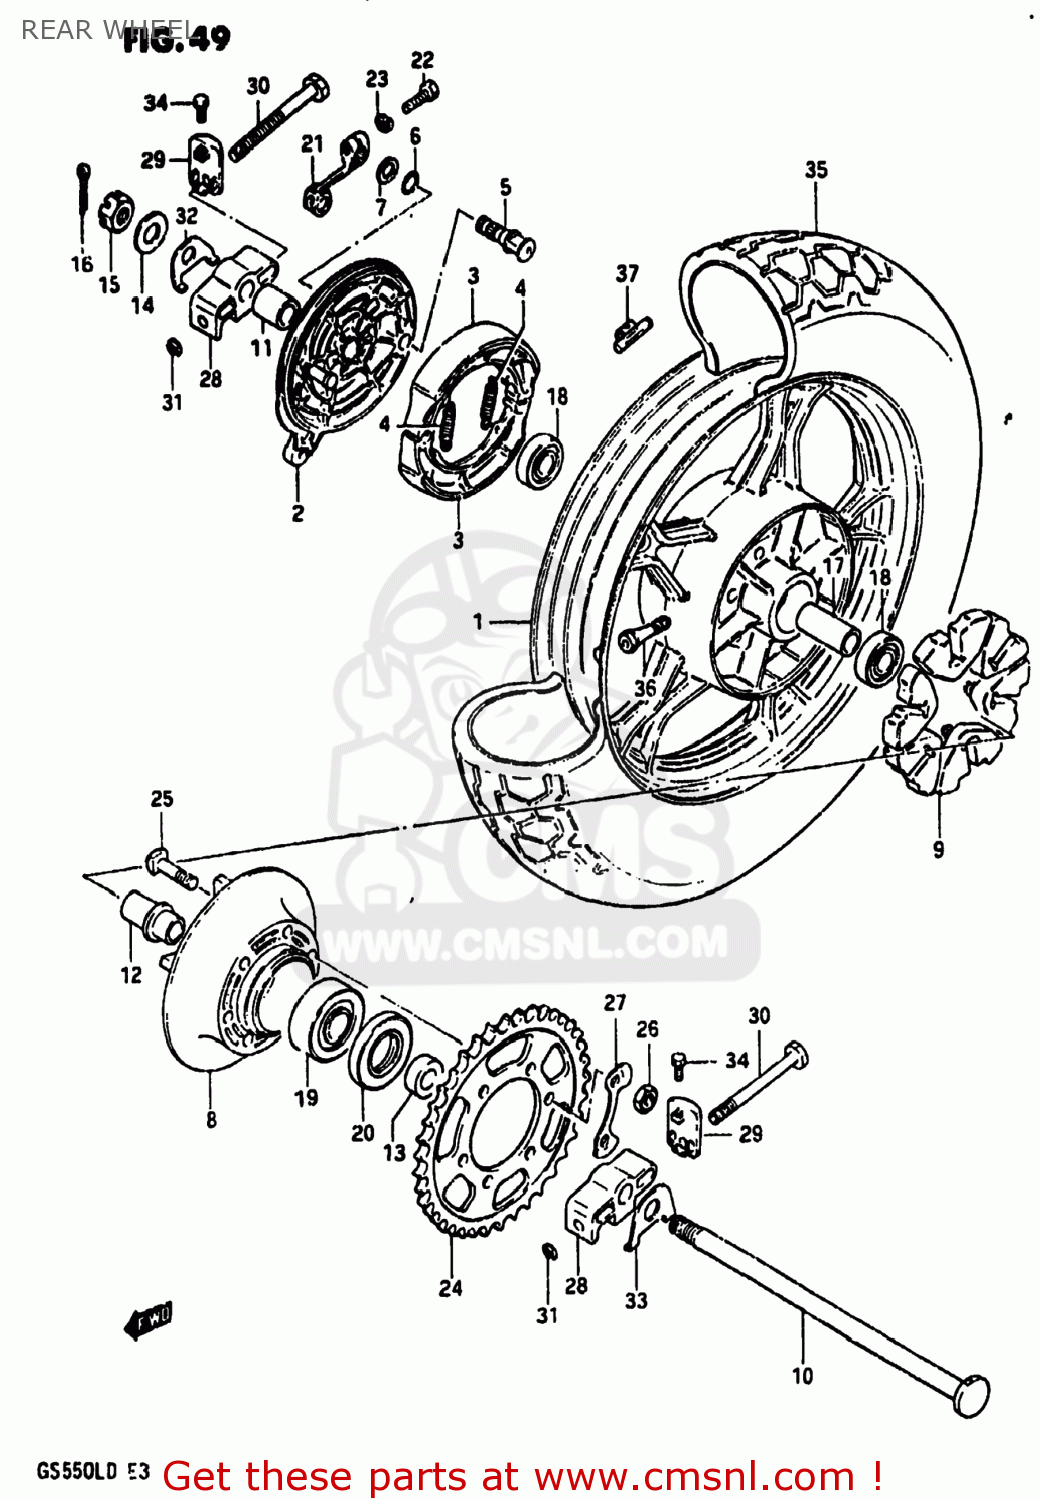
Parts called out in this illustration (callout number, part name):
1	WHEEL,REAR
2	PANEL,REAR HUB
3	SHOE,BRAKE
4	SPRING,BRAKE SHOE
5	CAM,FRONT BRAKE
6	O-RING,BOSS
7	WASHER (15X24X1.6)
8	DRUM,REAR SPROCKET MOUNT
9	ABSORBER,REAR HUB SHOCK
10	AXLE,REAR
11	SPACER (17.5X28X35)
12	RETAINER,RR SPROCKET DRUM
13	SPACER (17X33X12.5)
14	WASHER
15	NUT
16	PIN,COTTER
17	SPACER(17.5X25X70)
18	BEARING
19	BEARING
20	SEAL,OIL(33X62X7)
21	LEVER,REAR BRAKE CAM
22	BOLT
23	LOCK WASHER
24	SPROCKET,REAR
25	BOLT
26	NUT
27	WASHER
28	BODY,CHAIN ADJUSTER
29	PLATE,CHAIN ADJUSTER
30	BOLT,CHAIN ADJUSTER
31	E RING
32	WASHER,CHAIN ADJUSTER RH
33	WASHER,CHAIN ADJUSTER
34	BOLT(5X8)
35	TIRE
36	VALVE,TIRE
37	BALANCER,WHEEL
